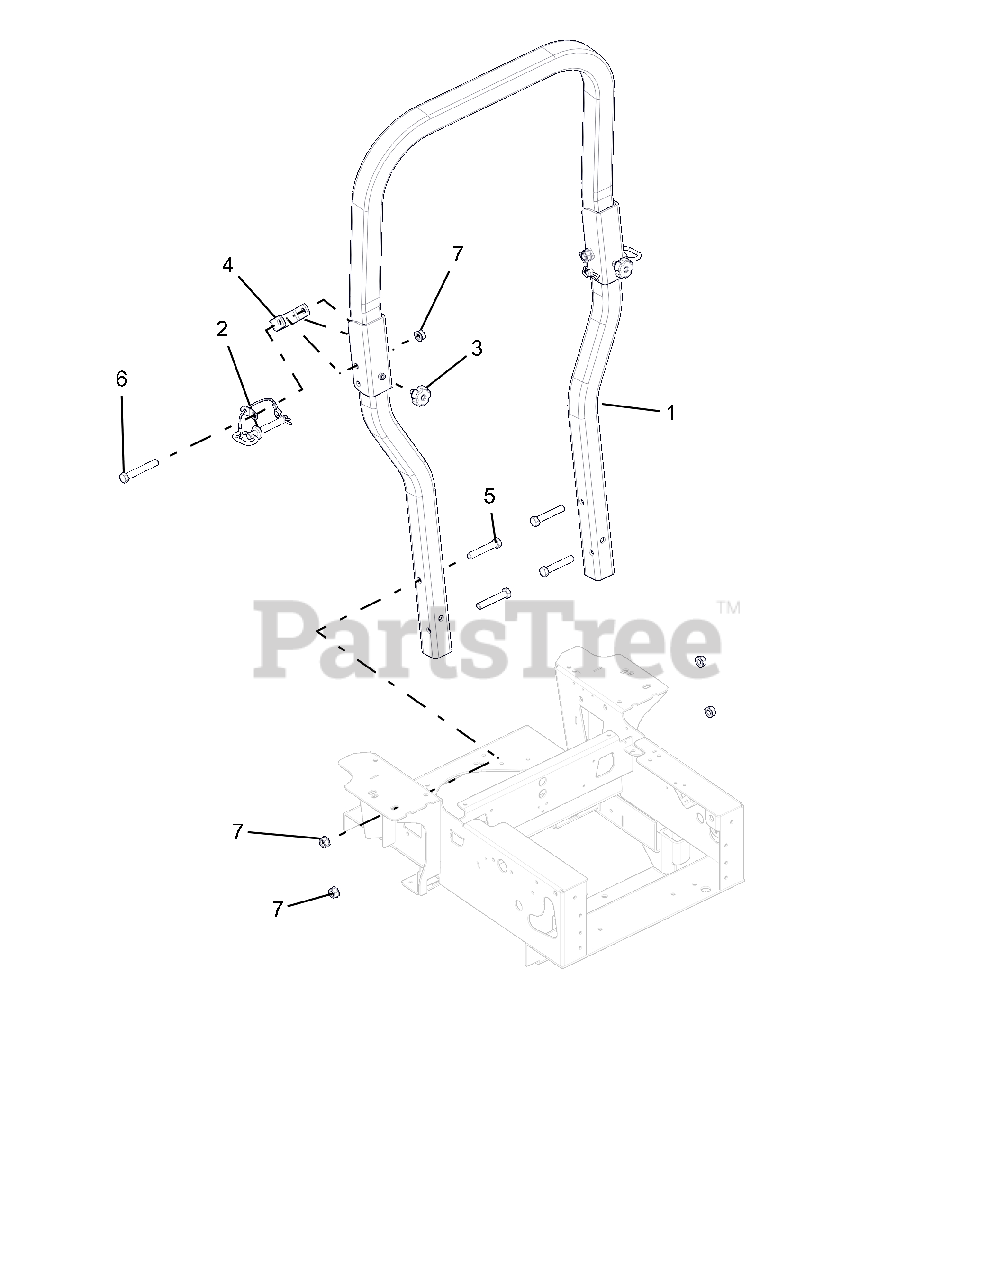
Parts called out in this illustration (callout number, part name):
1	ROPS, PT/PT100 REPLACEMENT
2	ASSY, ROPS PIN/LANYARD
3	KNOB, ROUND 5/16-18 X .750
4	BRKT, ROPS STOP, PRO-TURN YZ
5	BLT-HEX .50-13X3.00 GR5 YWZC
6	BLT-HEX .50-13X3.50 GR5 YWZC
7	NUT, LK-TOP-FLG .50-13 YWZC
